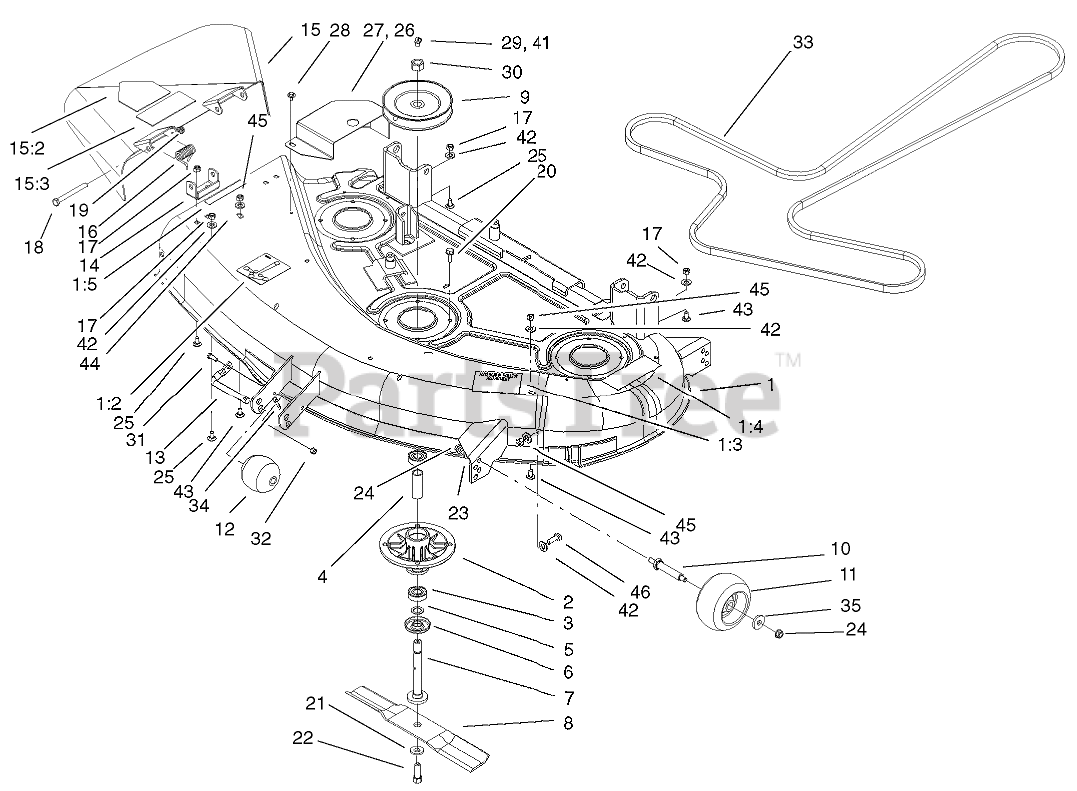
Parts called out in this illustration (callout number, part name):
1	44 INCH DECK ASM
1:2	DECAL-ROUTING, BELT
1:3	DECAL-WHEEL, GAGE
1:4	DECAL-DANGER
1:5	DECAL-CAUTION
2	HOUSING-SPINDLE
3	BEARING-BALL
4	SPACER - BEARING
5	SPACER
6	SHIELD-BEARING
7	SHAFT-CENTER, SPINDLE
9	PULLEY ASM
10	SPACER
11	WHEEL-GAGE
12	ROLLER
13	Shaft-Roller
14	BRACKET-PIVOT
15	DEFLECTOR/DECAL ASM
15:2	DECAL-DANGER
15:3	DECAL-DANGER
16	SPRING
17	NUT-LOCK, NI
18	SCREW-HH
19	NUT-HEX
20	SCREW-TAPTITE
21	WASHER-BELLEVILLE
22	SCREW-HH
23	WASHER-BELLEVILLE
24	NUT-HHF, WHIZ
25	SCREW-CARR
26	COVER-BELT, LH
27	COVER-BELT, RH
28	SCREW-HHFTF
29	FITTING-GREASE
30	NUT-HEX
31	SCREW-HH
32	NUT-LOCK, NI
34	PIN-COTTER
35	WASHER
41	FITTING-GREASE
42	WASHER-FLAT
43	SCREW-CARR
44	WASHER-FLAT
45	NUT-LOCK, NI
46	SCREW-HH
